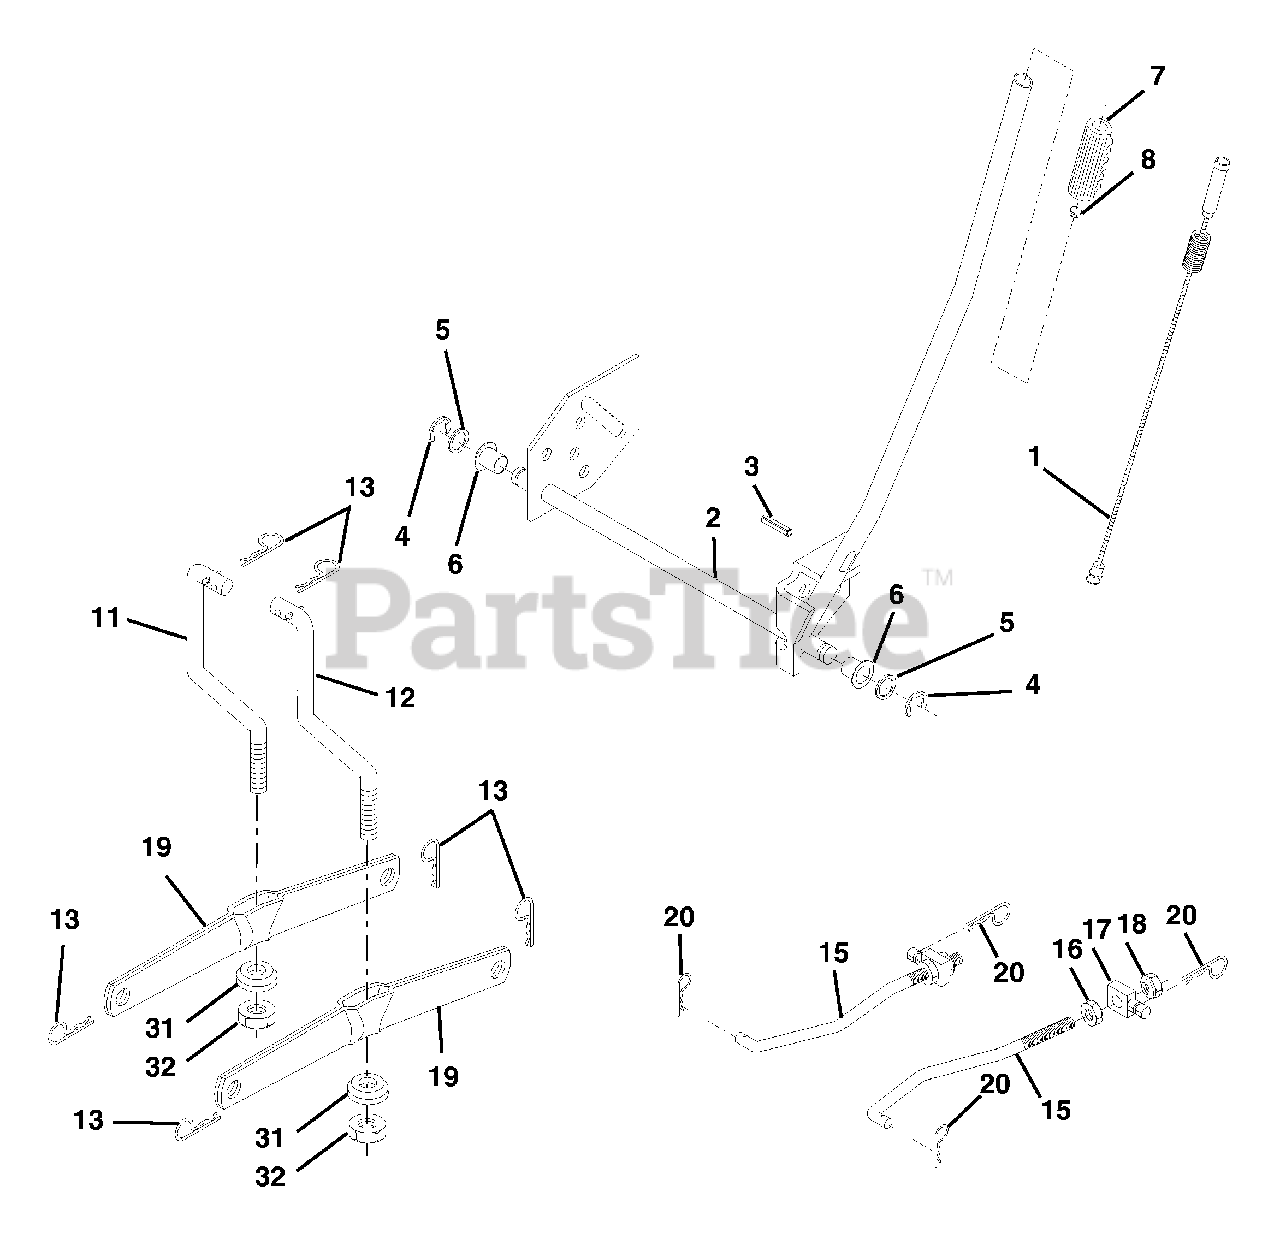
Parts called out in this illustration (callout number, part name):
1	Wire Asm Inner/Sprg W/plunger
2	Shaft Asm Lift RH w/Inf
3	Pin Groove 5/16 Dia x 1.875
4	E Ring #5133-62
5	Washer 21/32 x 1 x 21 Ga.
6	Bearing Nylon Blk 629 Id
7	Grip Handle
8	Button Plunger
11	Link Lift LH Fixed Length
12	Link Lift RH Fixed Length
13	Retainer Spring
15	Link Front
16	Nut Jam Hex 1/2-13 unc
17	Trunnion
18	Nut Lock W/Wsh 1/2-13 unc
19	Arm Suspension Rear
20	Retainer Spring
31	Bearing Pvt Lift
32	Nut Crownlock 3/8 - 24
